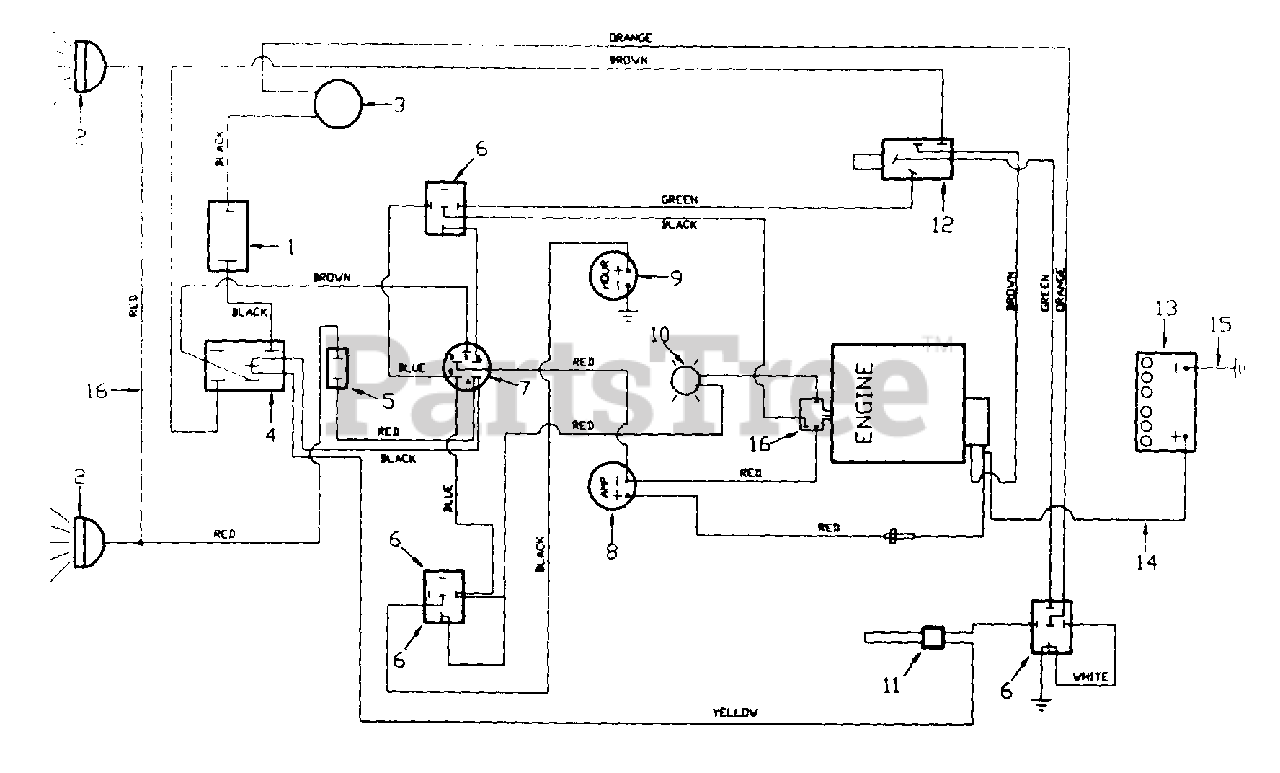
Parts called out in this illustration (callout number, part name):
1	CIRCUIT BREAKER - 10 amp
3	ELECTRIC CLUTCH
4	SWITCH - PTO
5	SWITCH - light
6	RELAY
7	IGNITION SWITCH (Onan)
13	BATTERY
